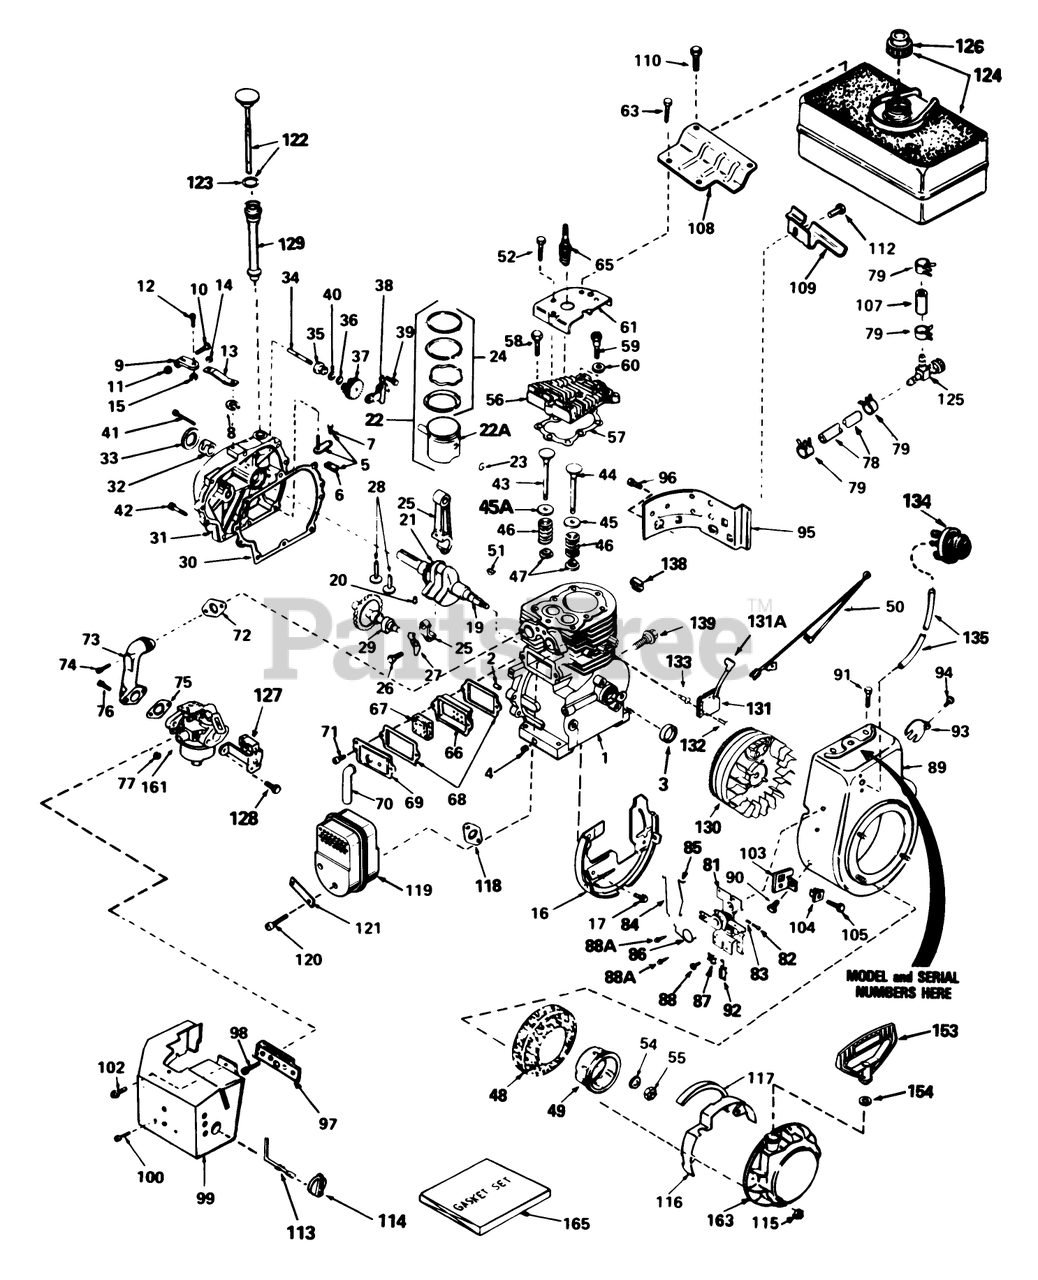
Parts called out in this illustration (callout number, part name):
1	Cylinder Assy. (Incl. Ref. #2, 3, 4 45A)
2	Pin-Dowel
3	Oil Seal
4	Plug-Drain, Oil (SQH 1/4-18)
5	Rod, Governor (Incl. Nos.62 63)
6	Yoke-Governor
7	Screw (6-40x5/16)
8	Ring-Retaining
9	Clamp-Lever, Governor
10	Screw
11	Nut-Lock
12	Screw
13	Lever-Governor
14	Washer-Lock
15	Nut-Lock
16	Baffle Blower Housing
17	Screw (1/4-20x19/32)
19	Crankshaft Assy. (Incl. Ref. #20 21)
20	Pin, Groove
21	Gear, Crankshaft
22	Piston, Pin Ring Assy.(Std.) (Incl. Ref. #24A, 25 26)
22	Piston, Pin Ring Assy. (.010 oversize) (Incl. Ref. #24A, 25 26)
22	Piston, Pin Ring Assy. (.020 oversize) (Incl. Ref. #24A, 25 26)
22A	Piston Pin Assy. (Std.) (Incl. Ref. #26)
22A	Piston Pin Assy. (.010 oversize) (Incl. Ref. #26)
22A	Piston, Pin Ring Assy. (.020 oversize) (Incl. Nos. 15 16)
24	Ring Set (Std.)
24	Ring Set (.010" OS)
24	Ring Set (.020" OS)
25	Rod Assy., Connecting (Incl. Nos. 10 18)
26	Bolt, Connecting Rod
27	Dipper-Oil
28	Lifter-Valve
29	Camshaft (Mech. Comp. Release)
30	Cylinder Cover Gasket
31	Cover, Cylinder (Incl. Ref. #32, 33 34)
32	Bushing, Crankshaft
33	Seal, Oil
34	Shaft-Governor
35	Spool-Governor
36	Ring-Retaining
37	Governor Gear ASM
38	Bracket-Gear, Governor
39	Screw (10-24x1/2)
40	Washer-Flat
41	Screw (1/4-20x1-3/16)
42	Screw (1/4-20x1-11/16)
43	Valve, Intake (Std.) (Incl. Ref. #58)
43	Valve, Intake (1/32" oversize) (Incl. Ref. #58)
44	Valve, Exhaust (Standard)(Incl. No. 9)
44	Valve, Exhaust (1/32" oversize)(Incl. No. 9)
45	Cap-Spring, Valve
45A	Seal-Intake Valve
46	Spring-Valve
47	Keeper-Spring, Valve
48	Screen, Starter
49	Cup-Starter
50	Ground Wire
51	Key-Flywheel
52	Screw (1/4-20 X 5/8)
54	Washer-Belleville
55	Nut-Flywheel
56	Head Cylinder
57	Gasket-Cylinder Head
58	Screw (5/16-18x1-1/2)
59	Screw (5/16-18x1-25/32)
60	Washer-Flat
61	Cover-Cylinder Head
63	Screw
65	Plug, Spark (J17LM or equiv.)
65	Plug, Spark (Champion RCJ-8)
66	Body-Breather
67	Element-Breather
68	Gasket-Breather
69	Cover-Valve
70	Tube-Breather
71	Screw
72	Gasket-Intake
73	Pipe-Intake
74	Screw (T-30, 5/16-18x1-3/32)
75	Gasket-Carburetor To Intake Pipe
76	Screw (1/4-28x1)
77	Nut and Lock Washer (1/4-28)
78	Line-Fuel
79	Clamp-Line, Fuel
81	Control Assy., Remote Speed (Incl. Ref. #90 thru 93)
82	Screw
83	Spring-Compression
84	Link-Governor
85	Link-Throttle
86	Spring-Throttle
87	Conduit
88	Screw (10-32 x 3/8)
88A	Screw (10-32 x 1/2)
89	Housing-Blower
90	Screw
91	Screw (5/16-18x3/4)
92	Terminal
93	Screw
94	Screw (8-32 x 3/8)
95	Extension-Housing, Blower
96	Screw
97	Bracket-Carburetor
98	Screw (8-32x27/64)
99	Cover-Carburetor
100	Screw (10-32 x 3/8)
102	Screw (10-32x1/2)
103	Bracket
104	Grommet
105	Screw
107	Line-Fuel (8.62)
108	Bracket-Tank, Fuel (Black)
109	Bracket-Tank, Fuel
110	Screw (1/4-15x7/8)
112	Screw (1/4-20x19/32)
113	Rod-Choke
114	Knob-Control
115	Nut and Lock Washer (1/4-28)
116	Guard, Starter
117	Seal, Snowguard
118	Gasket Exhaust
119	Muffler
120	Screw
121	62513 SNWTHWR W/284
122	Dipstick, Oil (Incl. Ref. #88)
123	O-Ring
124	Tank Assy., Fuel (Incl. No. 115)
125	Valve-Shut Off
126	Cap, Fuel
127	Bracket-Choke
128	Screw (10-32 x 1/2)
129	Tube Fill
130	Flywheel (W/Ring Gear)
131	Solid State ASM
131A	Cover-Spark Plug
132	Screw
134	Primer Assy.
135	Line-Primer
138	Clip-Wire
139	Screw (1/4-20x1/2)
153	Handle-Starter, Mitten Grip
154	Washer
161	Carburetor (Incl. Ref. #75)
163	Starter, Rewind
165	Gasket Set
